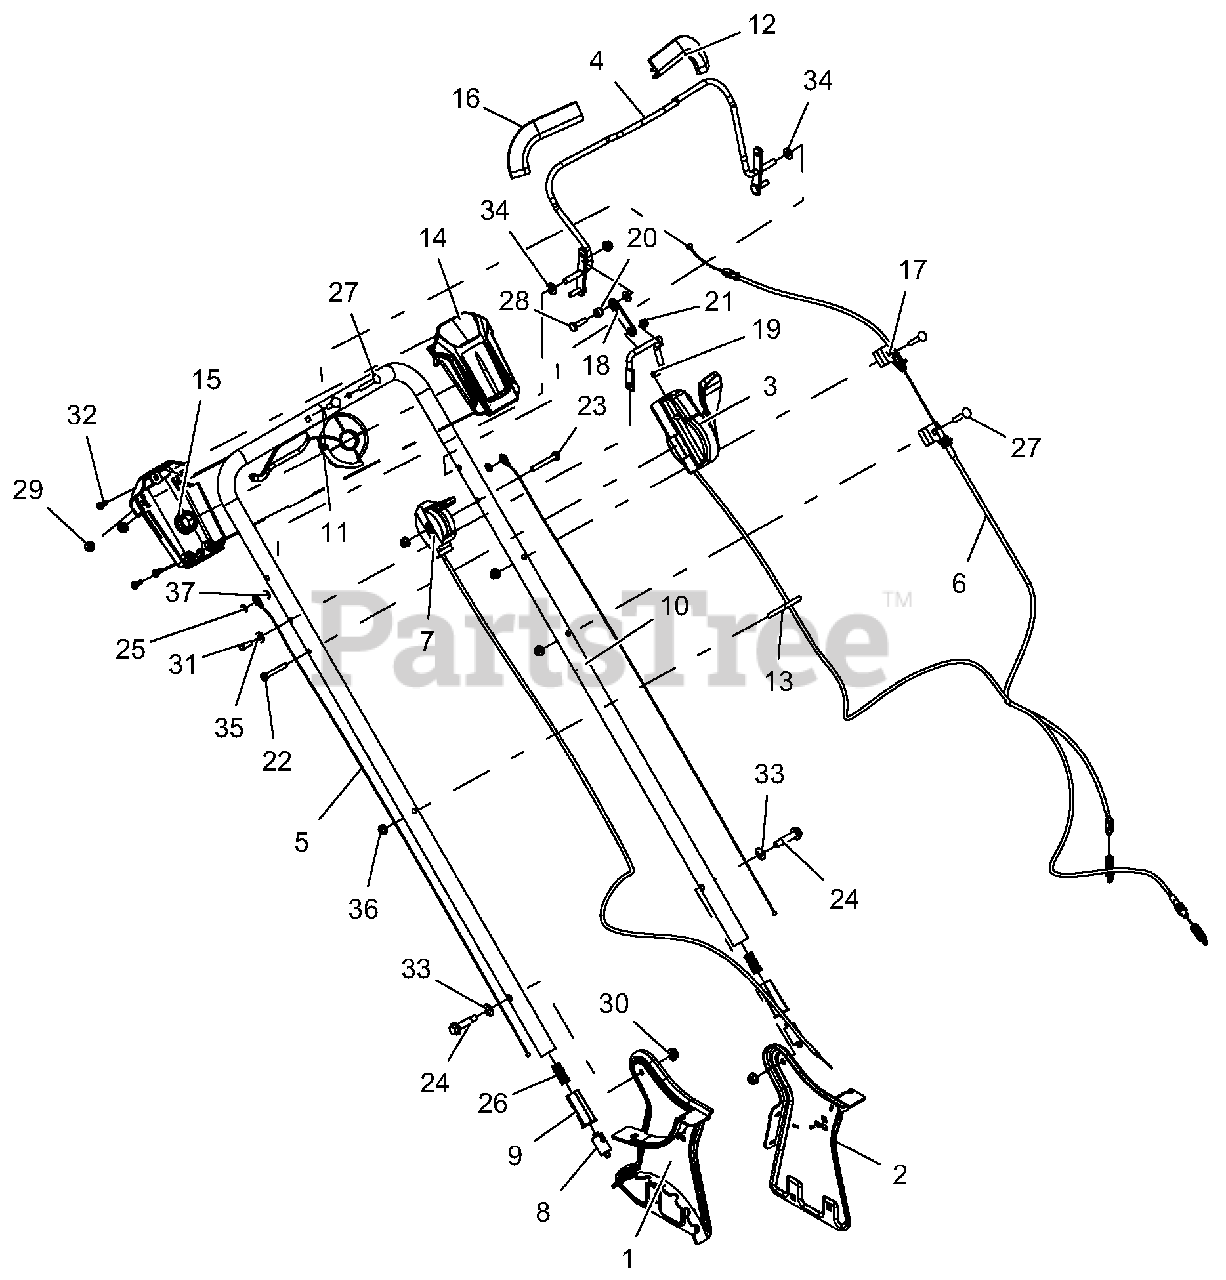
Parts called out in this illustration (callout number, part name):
1	WLDMT, RH SIDE PLATE
2	WLDMT, LH SIDE PLATE
3	ASM, BBC CONTROL
4	WLDMT, OPC BAIL, BBC
5	CABLE, LM HANDLE ADJUST
6	CABLE, DRIVE CONTROL
7	CONTROL, THROTTLE
8	PIN, LM HANDLEBAR LOCKING
9	HANDLEBAR ADJUSTMENT INSERT
10	HANDLEBAR, LM
11	HANDLE, DRIVE CONTROL
12	GUARD, FINGER - LH
13	GUIDE, RECOIL ROPE
14	HOUSING, UPPER DRIVE CONTROL
15	HOUSING, LOWER DRIVE CONTROL
16	GUARD, FINGER - RH
17	BRKT, CABLE - DRIVE
18	COUPLER, LINK
19	WIREFORM, BBC CONTROL
20	BSHG, BBC LATCH
21	BUSHING, NYLON .31, SPLIT
22	SCR, MACHINE M6-1X45 PANHD
23	SCREW, MACHINE .25-20X2.00 PH PAN
24	BLT, SHLDR .50X1.30X.38-16 GR5
25	NUT, PUSH .25X.50 O.D.
26	SPRG, COMPRESSION
27	BLT-RDHDSQNK .25-20X1.50 G5 Y
28	BLT-HEX .25-20X1.00 GR5 YWZC
29	NUT, LK-TOP-FLG .25-20 YWZC
30	NUT, LK-TOP-FLG .312-18 YWZC
31	PIN, CVS .250X.750X.609 YWZC
32	SCR-TAP #12-14X.75 PLASTITE BLZC
33	WSHR-FL-STL .385x.745x.030 YWZC
34	WSHR-FL-STL.344X.688X.065YWZC
35	WSHR-FL-STL.281X.62X.065 YWZC
36	NUT-LK-NYL-FLG .25-20 YWZC
37	RG-RTNG-EXT .250 X .010
